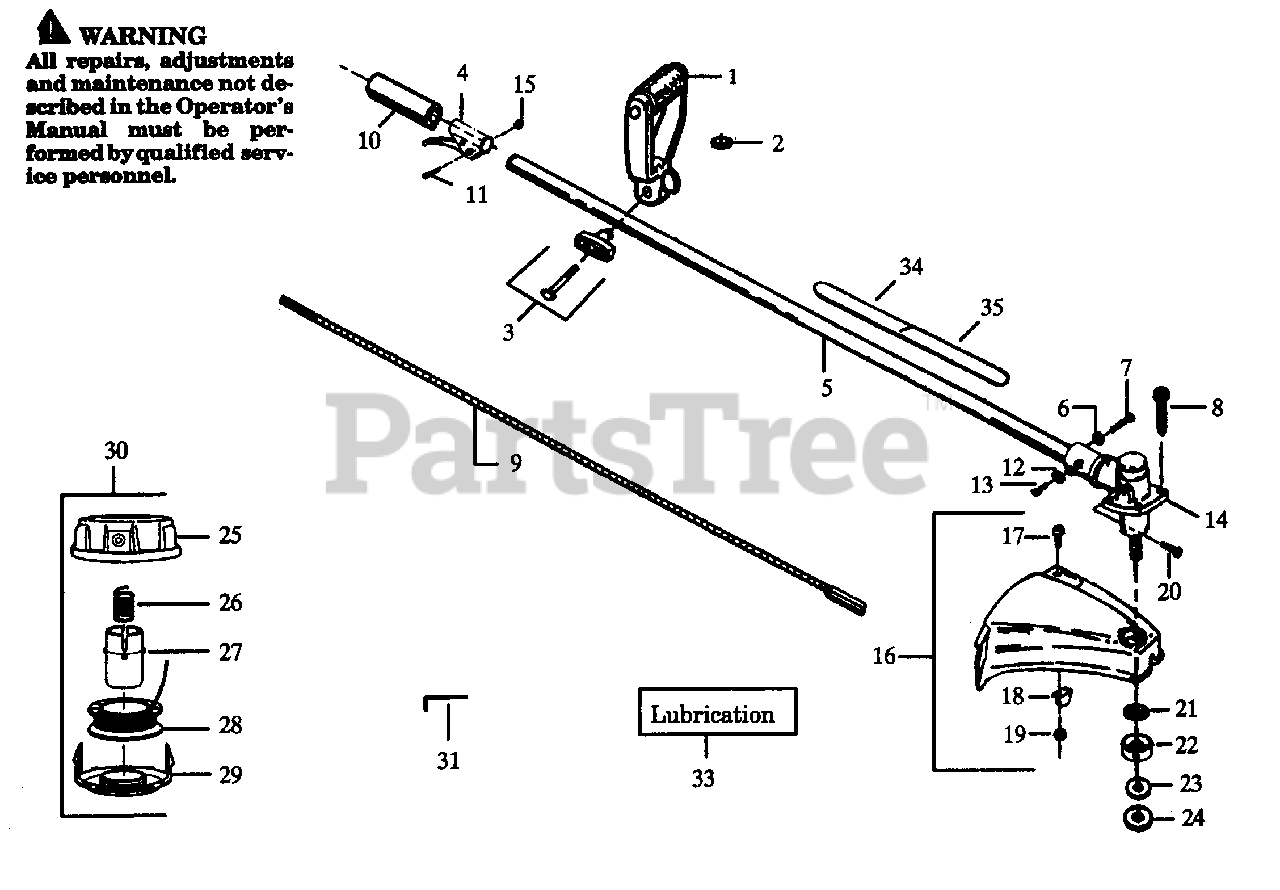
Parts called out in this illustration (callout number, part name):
3	"T" Handle Ass'y.
4	Throttle Hsg. Ass'y.
5	Drive Shaft Housing
6	Lockwasher
8	Screw
9	Drive Shaft
12	Lockwasher
14	Gear Box Assy.
16	Shield Kit Assy.
18	Line Limiter
19	Locknut
22	Dust Cup
23	Grass Washer
25	Hub Assy.
27	Release Button
28	Spool w/Line
30	Cutting Head Ass'y
31	Hex Wrench (5/32)
33	Shaft Lubrication
34	Shaft Warning Decal-Upper
35	Shaft Warning Decal-Lower
